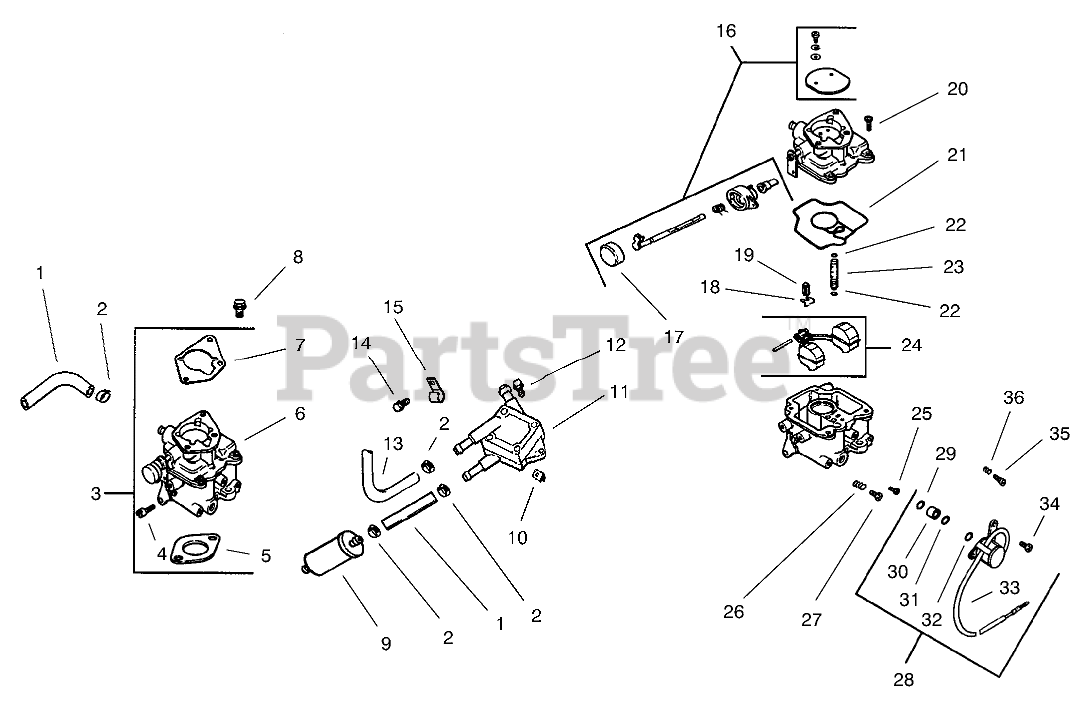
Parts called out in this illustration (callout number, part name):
1	Line fuel
2	Clamp
3	Kit, carburetor w/gasket (Includes 4-7)
4	Screw-Throttle Stop
5	Gasket
6	Carburetor assembly (Includes 16-36, carburetor repair kit 24 757 03)
7	Gasket
8	Screw
9	Filter-Fuel
10	Nut
11	Pump-Fuel
12	Screw
13	Line, fuel17"
14	Screw
15	Clamp
16	Kit, choke repair (Includes 17)
17	Cap-Choke Lever
18	Clip, cable
19	Valve-Inlet Needle
20	Screw
21	Gasket-Body,Carburetor
22	"O"Ring
23	Jet-Slow
24	Roat Repair Kit
25	Jet-Main
26	Spring-Idle Speed Adj.
27	Screw, idle adjusting
28	Kit, solenoid (Includes 29-34)
29	O-Ring
30	Seat-Solenoid
31	O-Ring
32	O-Ring
33	Solenoid
34	Screw
35	Needle, idle
36	Spring-Idle Adj.
